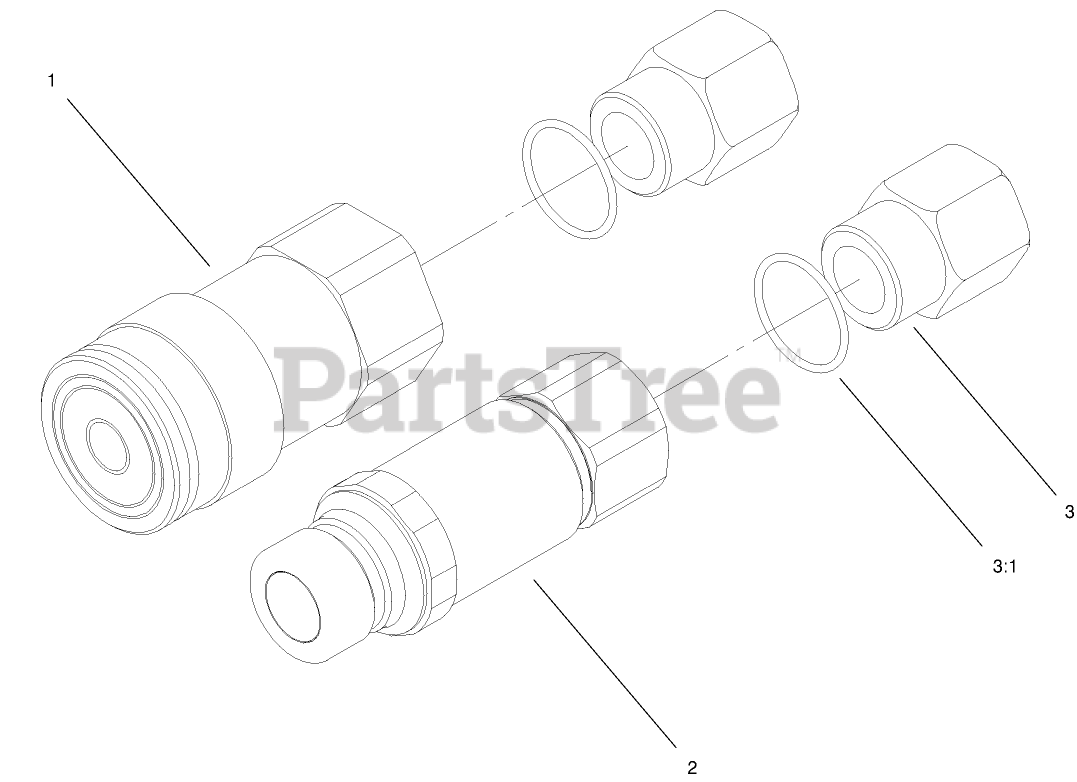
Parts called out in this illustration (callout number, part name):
1	COUPLER-FACE, FLUSH
2	NIPPLE-CONNECT, PRESSURE
3	ADAPTER-HYD
3:1	O-RING
